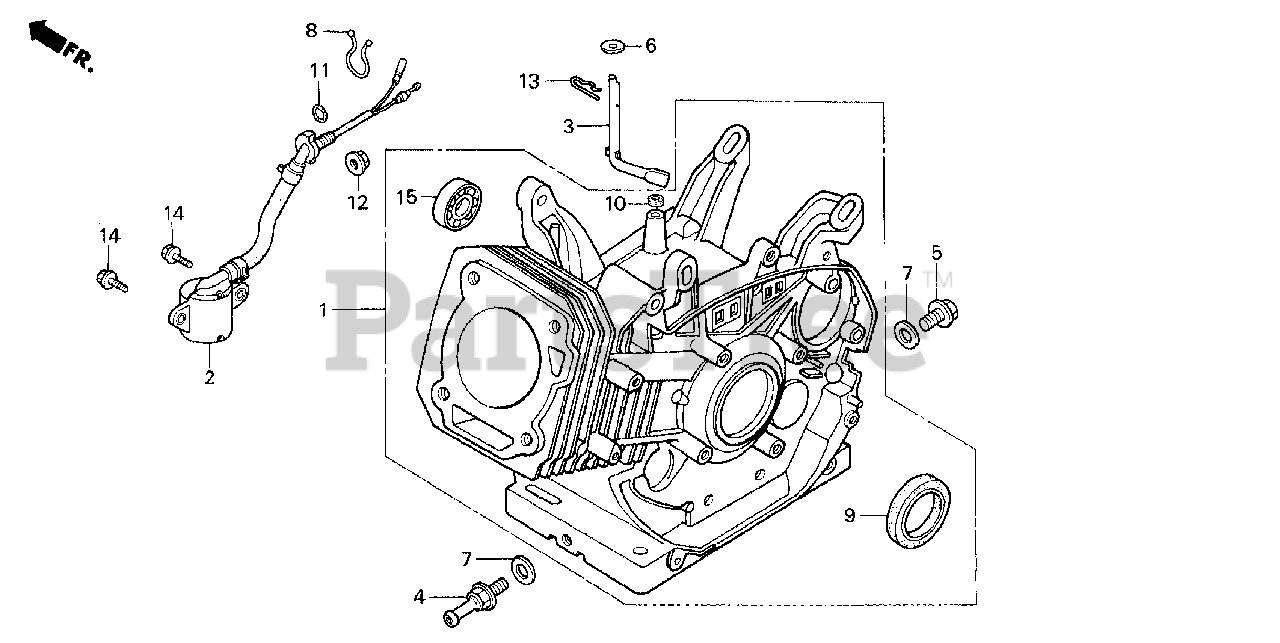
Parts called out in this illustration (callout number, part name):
1	CYLINDER ASSY. (L04)
2	SWITCH ASSY., OIL LEVEL
3	SHAFT, GOVERNOR ARM
4	PLUG, OIL DRAIN
5	BOLT, DRAIN PLUG
6	WASHER (8.2X17X0.8)
7	WASHER, DRAIN PLUG (12MM)
8	CLIP, PURSE LOCK
9	OIL SEAL (35X52X8)
10	OIL SEAL (8X14X5)
11	O-RING (14MM) (ARAI)
12	NUT, FLANGE (10MM)
13	PIN, LOCK (8MM)
13	PIN, LOCK (10MM)
14	BOLT, FLANGE (6X12)
15	BEARING, RADIAL BALL (6202)
